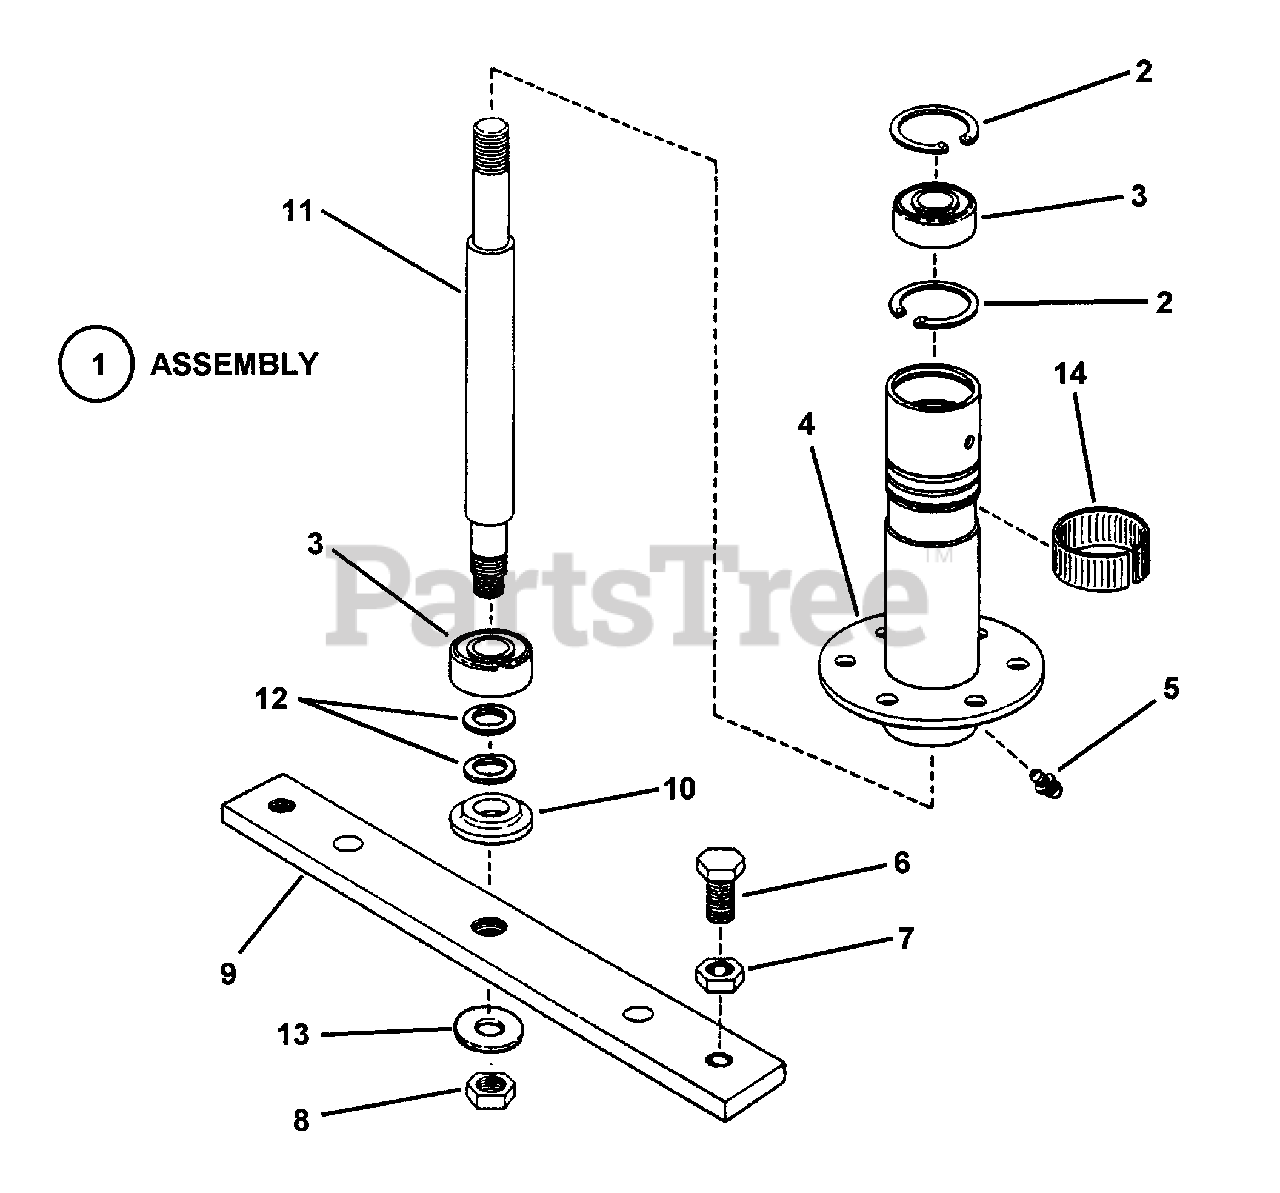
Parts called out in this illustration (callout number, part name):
1	ASSEMBLY, Spindle Housing
2	RING, 1.85" Internal Retaining
3	BEARING, Spindle
4	WELDMENT, Spindle Housing
5	FITTING, Lube (Press fit for .187 hole-no ball)
6	SCREW, 1/2-20 x 1-1/4" Hex Head Cap, Grade 5
7	NUT, 1/2-20 Hex Jam
8	NUT, 5/8-18 Hex Center Lock
9	HOLDER, Blade
10	WASHER, Spindle
11	SPINDLE, Shaft (10.237" Long)
12	WASHER, 49/64" Shim
13	SPACER, Blade Centering
14	RING, 2" Tolerance
